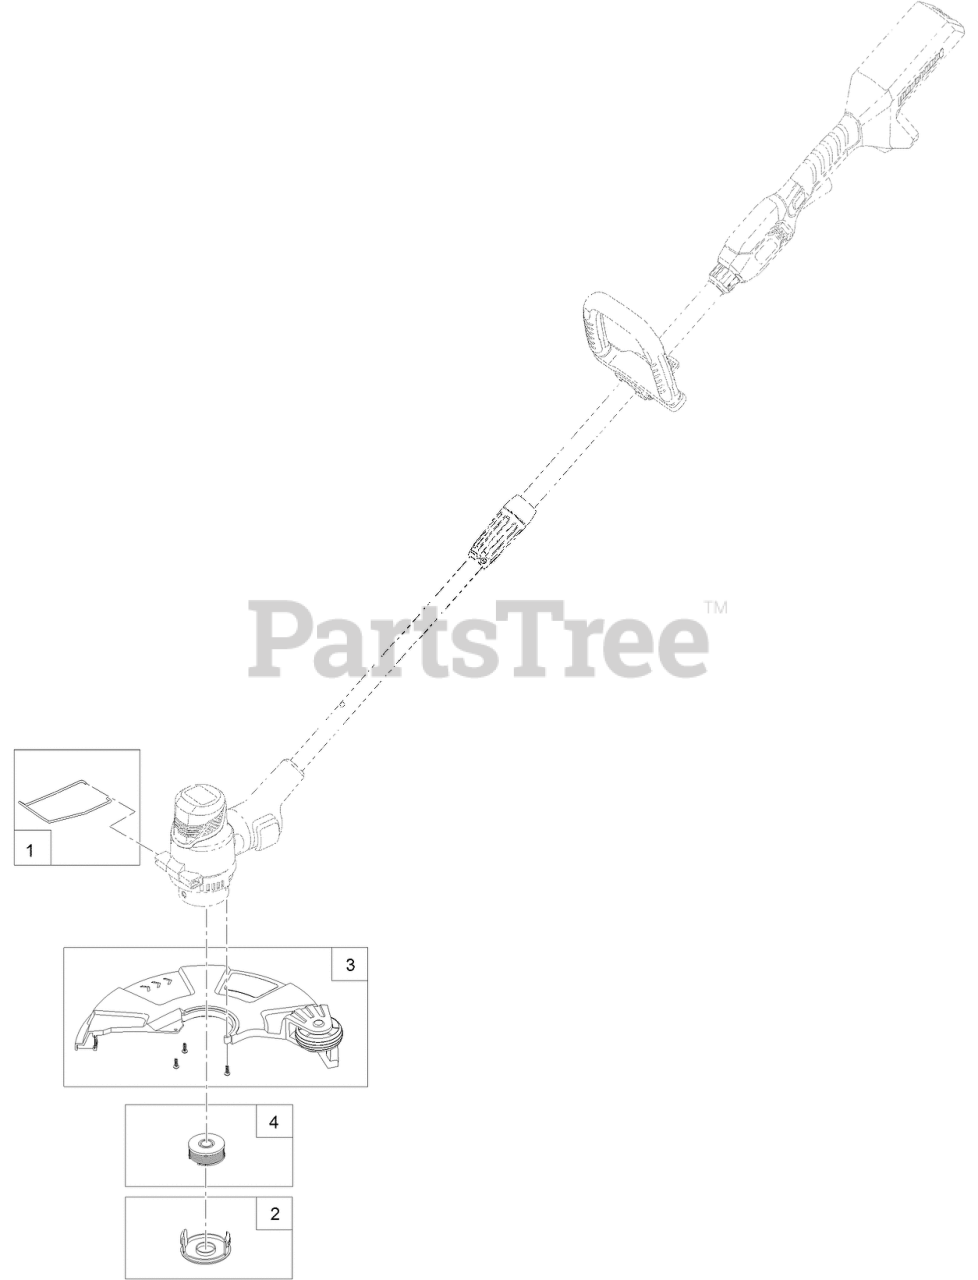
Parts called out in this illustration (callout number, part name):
1	CLIP-WIRE, GUIDE
2	CAP-RETAINER, SPOOL
3	GRASS SHIELD ASM
4	3-PACK SINGLE-LINE SPOOL
